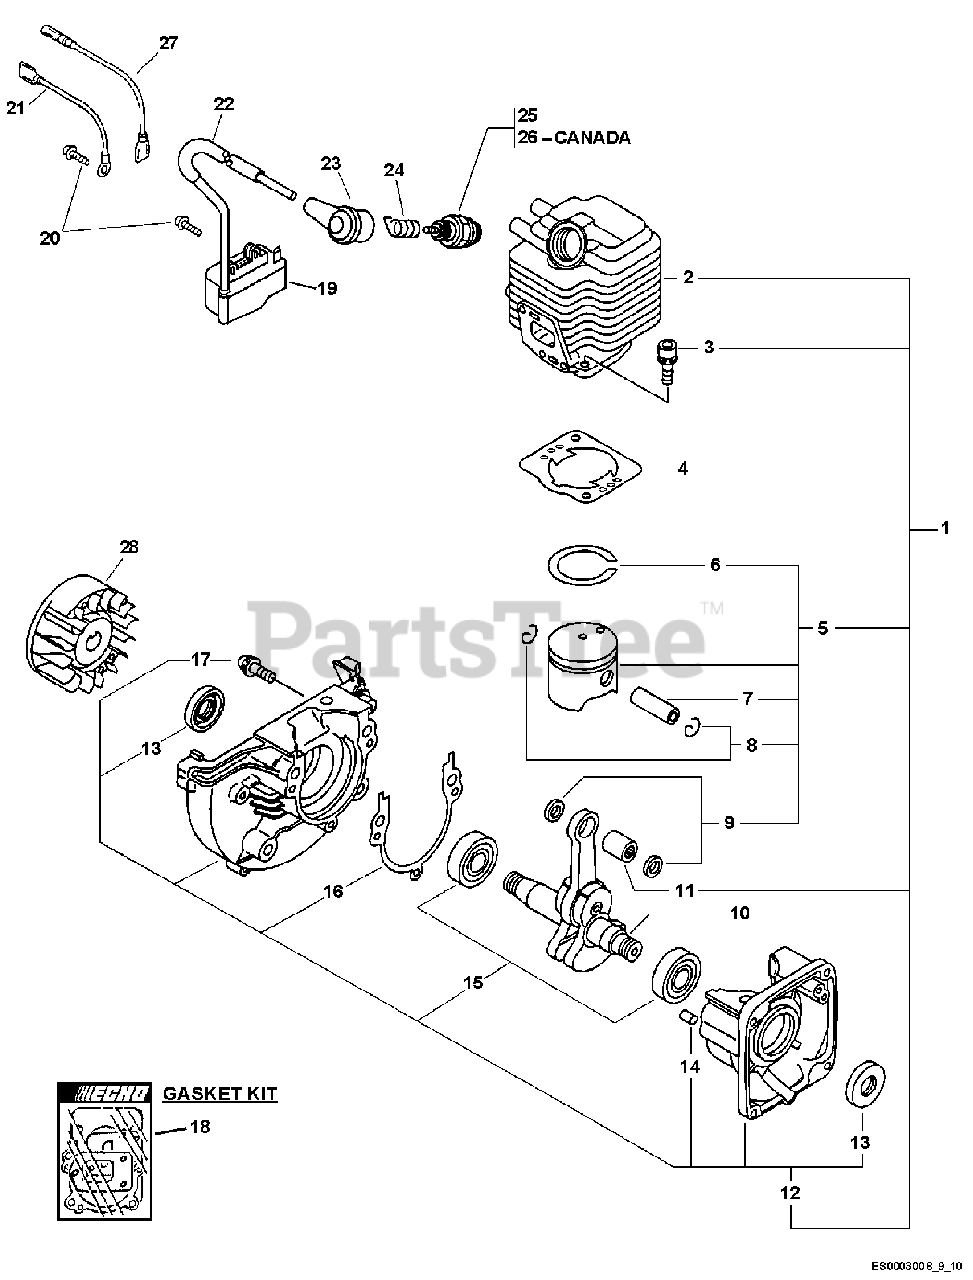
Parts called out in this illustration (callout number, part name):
1	SHORT BLOCK -- SB1076
2	CYLINDER
3	SCREW - 5X22
4	GASKET, CYLINDER
5	PISTON KIT
6	RING, PISTON
7	PIN, PISTON
8	RING, RETAINING
9	SPACER, PISTON
10	CRANKSHAFT ASSY
11	BEARING, NEEDLE - 8
12	CRANKCASE KIT
13	SEAL, OIL
14	PIN - LOCATING
15	BEARING, BALL - 6201
16	GASKET, CRANKCASE
17	SCREW - 5X28
18	GASKET KIT
19	COIL, IGNITION
20	SCREW - 4X20
21	LEAD - GROUND
22	TUBE, INSULATOR
23	CAP, SPARK PLUG
24	TERMINAL, SPARK PLUG CAP
25	SPARK PLUG -- BPM-8Y
26	SPARK PLUG -- BPMR-8Y
27	LEAD - IGNITION
28	FLYWHEEL
